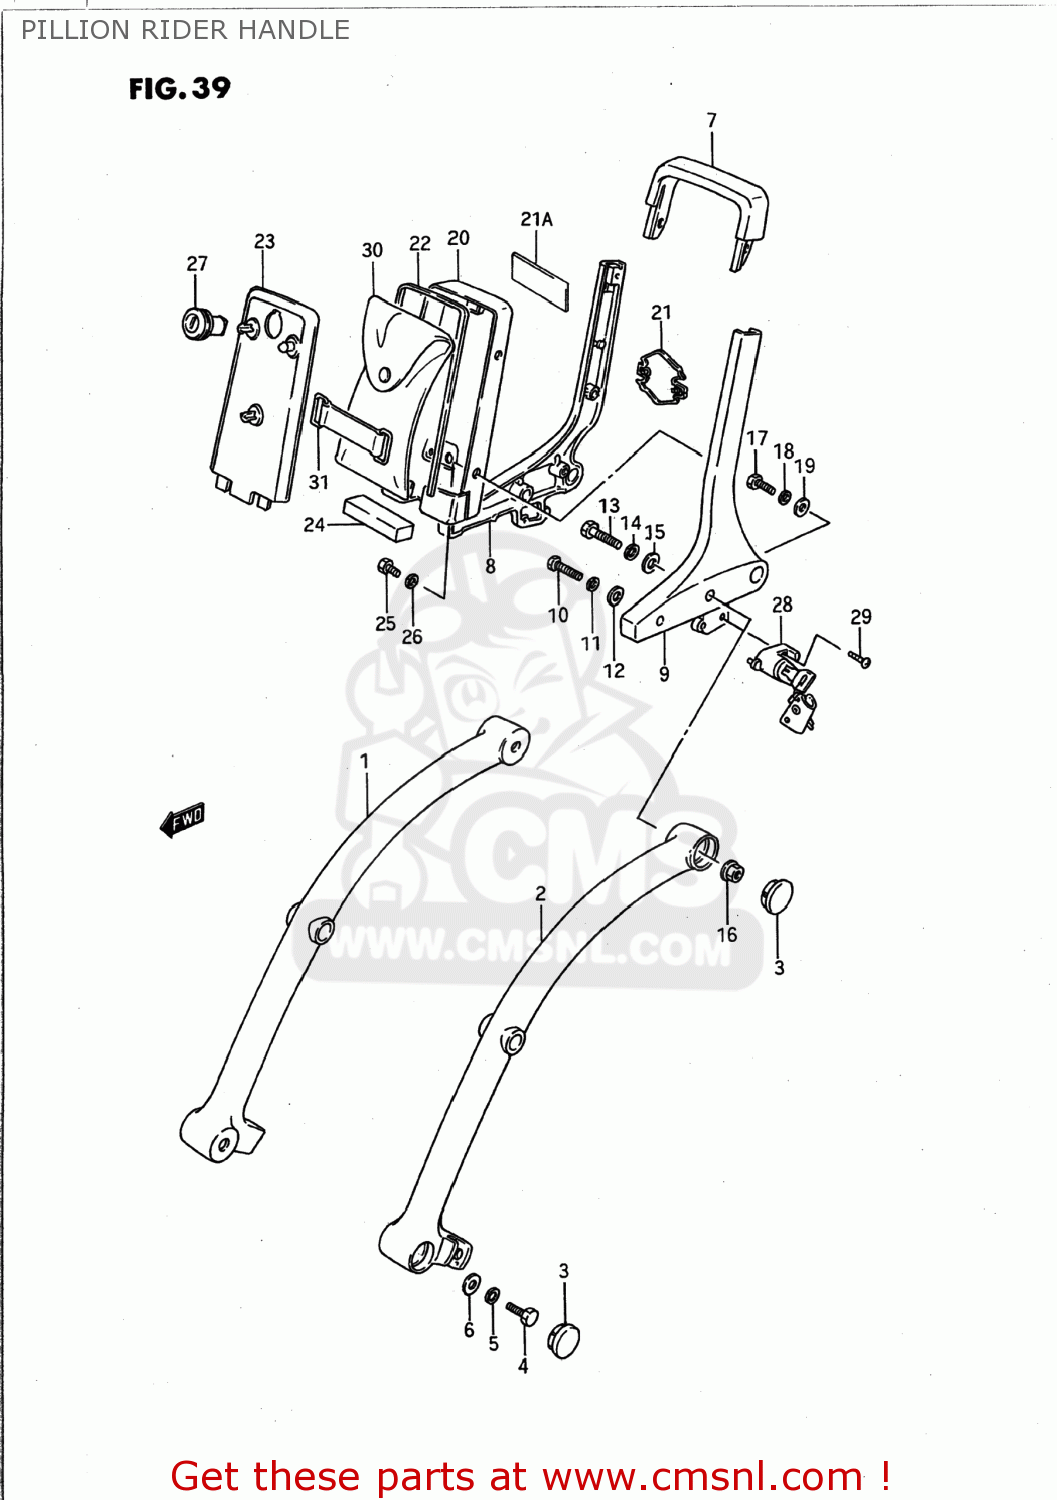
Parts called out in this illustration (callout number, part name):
1	GRIP COMP,FRAME HANDLE
2	GRIP COMP,FRAME HANDLE
3	CAP,PIPE CO-RIDER GRIP
4	BOLT
5	WASHER,LOCK
6	WASHER
7	HANDLE,PILLION RIDER
8	HANDLE,PILLION RIDER
9	HANDLE,PILLION RIDER
10	BOLT
11	LOCK WASHER
12	WASHER
13	BOLT
14	LOCK WASHER
15	WASHER
16	NUT
17	BOLT
18	LOCK WASHER
19	WASHER
20	HOLDER,TOOL
21	EMBLEM
21A	TAPE,TOOL BAG PROTECTOR
22	MOLDING,TOOL HOLDER RR
23	HOLDER,TOOL FR
24	CUSHION,TOOL BACK
25	BOLT
26	WASHER,LOCK
27	LOCK SET,TOOL HOLDER
28	LOCK SET,HELMET
29	SCREW
30	TOOL ASSY
31	BAND
32	CARRIER ASSEMBLY,REAR
